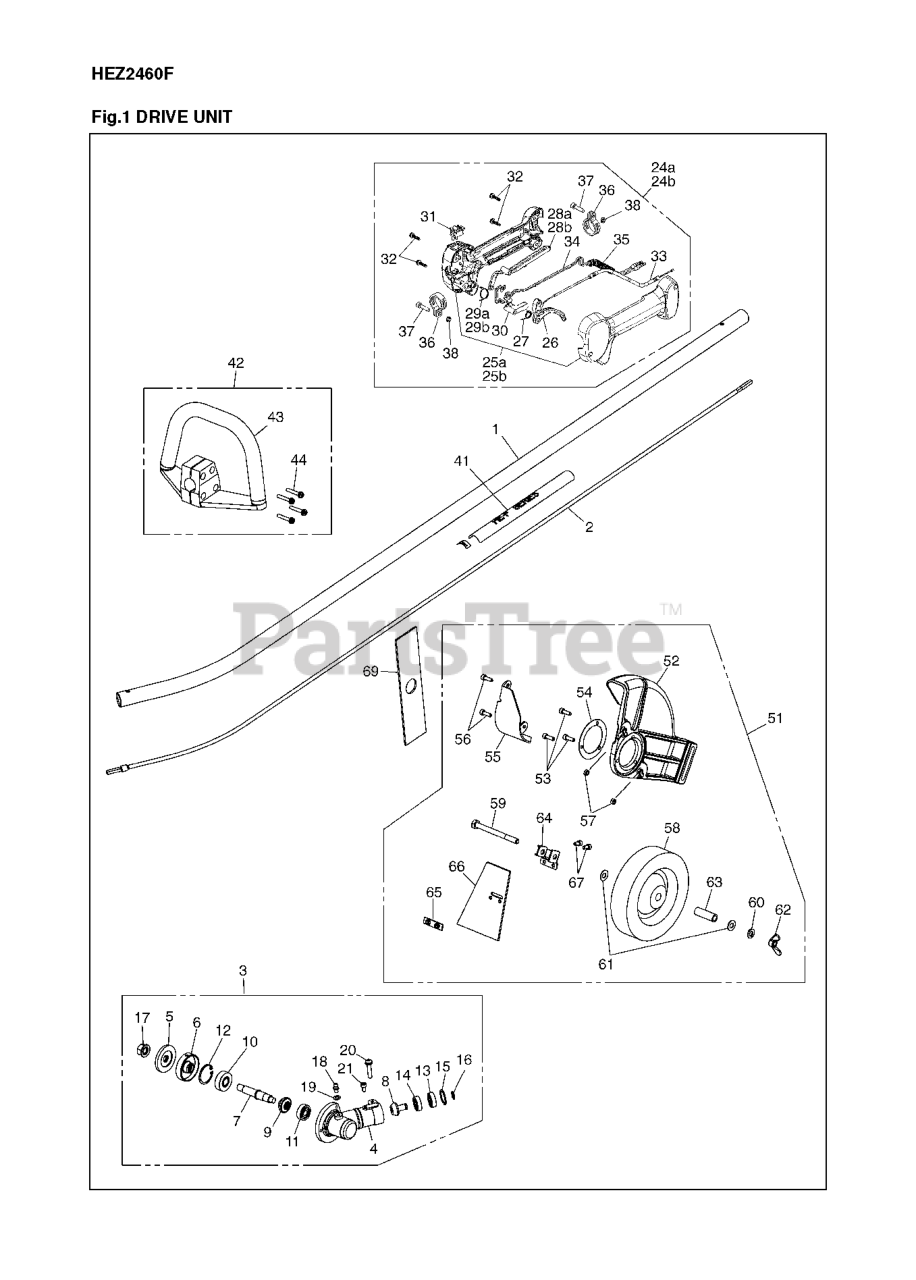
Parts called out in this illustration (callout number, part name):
1	PIPE COMP
2	FLEX SHAFT
3	GEARCASE ASSY
4	GEARCASE
5	HOLDER(B)
6	HOLDER(A)
7	SHAFT.GEAR
10	BEARING***
21	BOLT M5 X L10 ALLEN BOLT
24	GRIP ASSY
25	GRIP HALF SET
26	LEVER, THROTTLE
27	SPRING, THROTTLE
28	LEVER FOR GRIP (RPLS -0600)
28	LEVER, SAFETY
29	SPRING JOINT
29	SPRING
30	LEVER JOINT
34	CORD - C
38	NUT
41	NAME PLATE HEZ2460F
42	HANDLE ASSY. (RPLS T319514001)
43	HANDLE T
51	GUARD ASSY
52	GUARD
53	BOLT M5 X L16 ALLEN
55	PROTECTOR
56	BOLT M5 X L16 ALLEN
67	BOLT M5 X L10 ALLEN BOLT
69	Edger Blade
